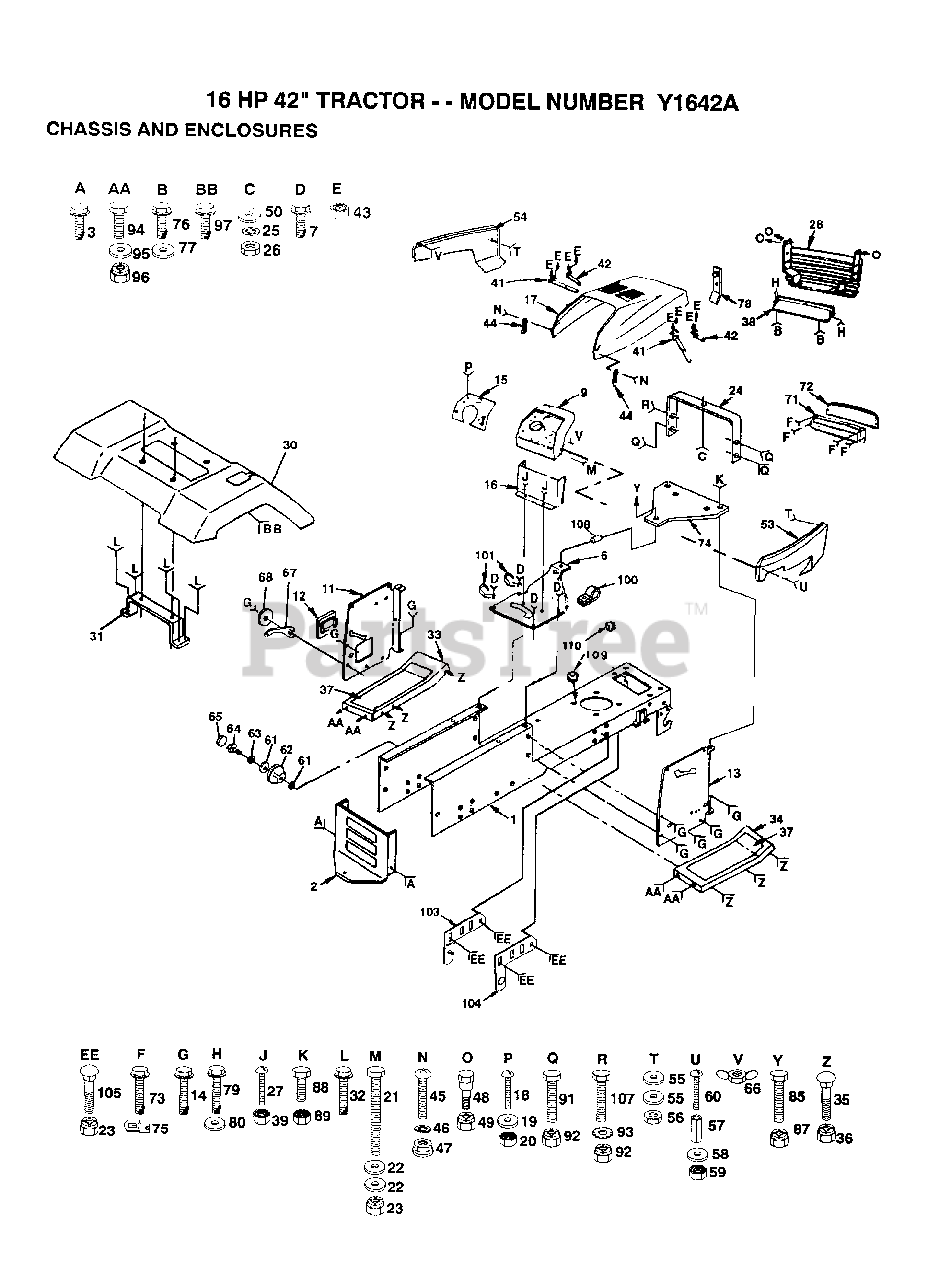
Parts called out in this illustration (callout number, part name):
3	SCREW
7	SCREW LT
11	PANEL DASH LH
12	COVER ACCESS
13	DASH PANEL RH
14	SCREW
16	DASH ASSY LT
18	SCREW
19	WASHER
22	WASHER
24	SUPPORT ASS'Y
25	LOCKWASHER
27	SCREW
32	SCREW
35	BOLT
37	FOOTREST PAD
43	NUT
44	HOOD LATCH T
45	SCREW
46	LOCKWASHER
47	WELDNUT
50	WASHER PM
53	"PANEL,SIDE RH"
54	"PANEL,SIDE LH"
55	WASHER PM
57	SPACER LT
58	WASHER
60	SCREW
61	WASHER
62	HEIGHT INDICATOR
63	LOCKWASHER
65	"PLUG,HOLE"
68	WASHER T
72	LENS LT
75	"""J"" FASTENER LT"
76	SCREW
77	WASHER
79	SCREW HEX CRT
80	WASHER
85	BOLT
89	NUT
93	LOCKWASHER
95	WASHER
97	SCREW LT
100	CLIP T
101	CLIP T
103	PIVOT BRKT LH
104	PIVOT BRKT RH
105	BOLT
107	BOLT
108	SPACER
109	SNAP BUSHING T
